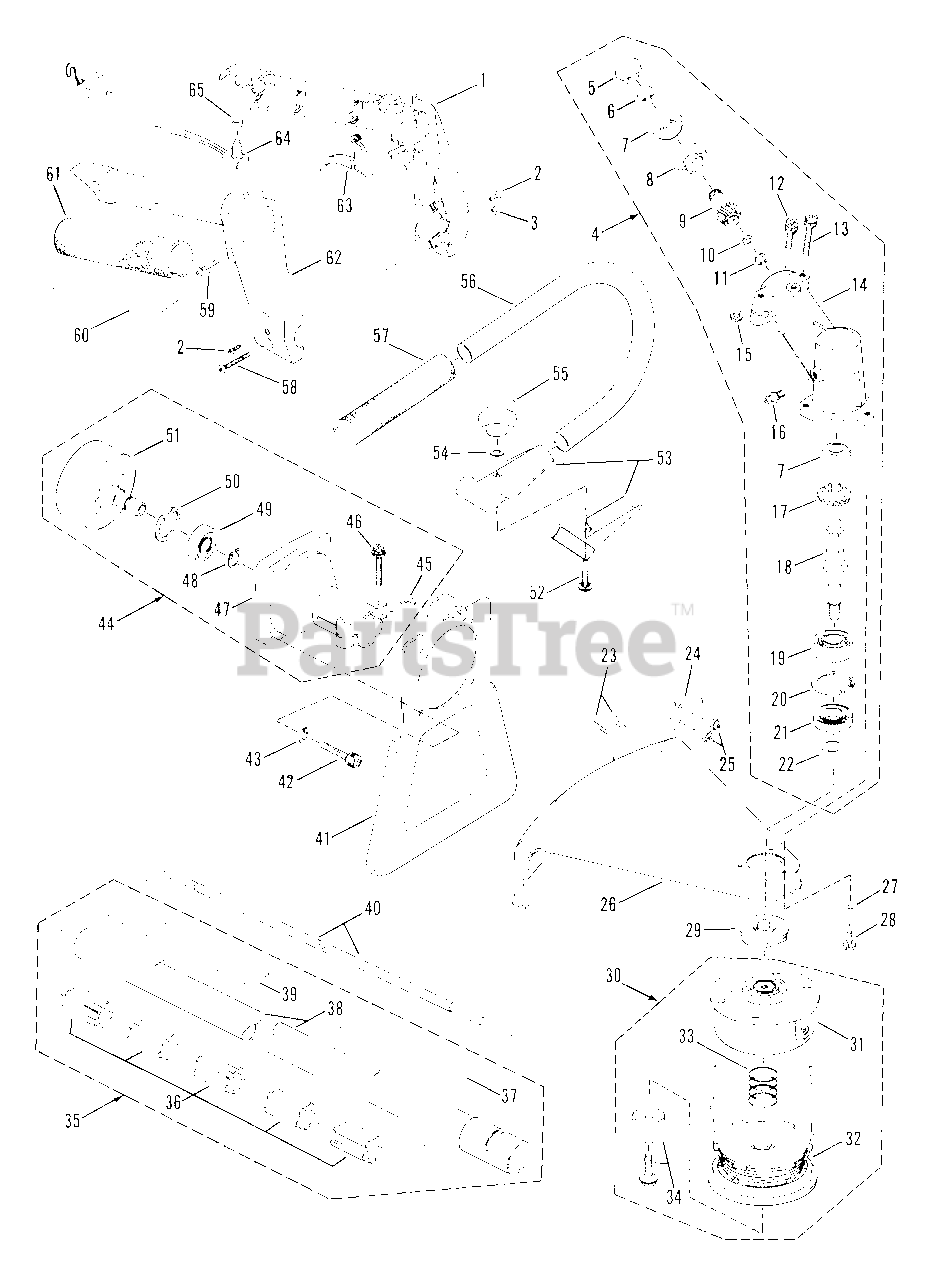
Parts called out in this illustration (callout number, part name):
1	HANDLE, Left Half
2	SCREW, TORX, #6 x 5/16"
3	LOCKNUT, #10-32
4	GEAR HEAD ASSM'Y
5	SNAP RING, 26mm
6	SNAP RING, 10mm
7	BEARING
8	BEARING
9	BEVEL PINION
10	WASHER, Flat
11	SNAP RING, 10mm
12	BOLT, M5 x 12mm Hex Hd.
13	BOLT, M5 x 25mm Hex Hd.
14	GEAR CASE
16	FITTING, Lube
17	BEVEL GEAR
18	SPLINE SHAFT
19	BEARING
20	SNAP RING, 35mm
21	SEAL, Oil
22	SPLINE SLEEVE
23	SCREW, #10-32 x 5/8"
24	CUTTER,Line
25	LOCKNUT, #10-32
28	BOLT, M5 x 16mm
29	HOLDER
30	BUMP HEAD ASSM'Y.
32	SPOOL & LINE
33	SPRING
34	KNOB & BOLT
35	ASSEMBLY, Tubing & Bushings
36	BEARING ASSM'Y.
37	DECAL-WARNING (Eye Protection)
38	TUBE-DECAL ASSM'Y.
39	DECAL-SNAPPER
40	SHAFT, Main (55.12"x.25", .2" square ends x 1")
41	STAND, Engine
42	SCREW, M6 x 25mm Socket
43	LOCKWASHER
44	CLUTCH CASE ASSM'Y.
45	WASHER, Shim
46	BOLT, M5 x 25mm Hex Hd., W/Washers
47	CASE, Clutch
48	SNAP RING, 12mm
49	BEARING
50	SNAP RING, 28mm
51	DRUM, Clutch
52	SCREW, 5/16C x 1 3/4"
53	CLAMP, Half
54	WASHER
56	HANDLE, "J"
57	GRIP, "J"
58	SCREW, #10-32 x 7/8"
59	SCREW, #10-16 x 3/4"
60	STRIP, Adhesive
61	GRIP, Handle
62	HANDLE, Right Half
63	TRIGGER
64	SWITCH
65	CAP, Switch
